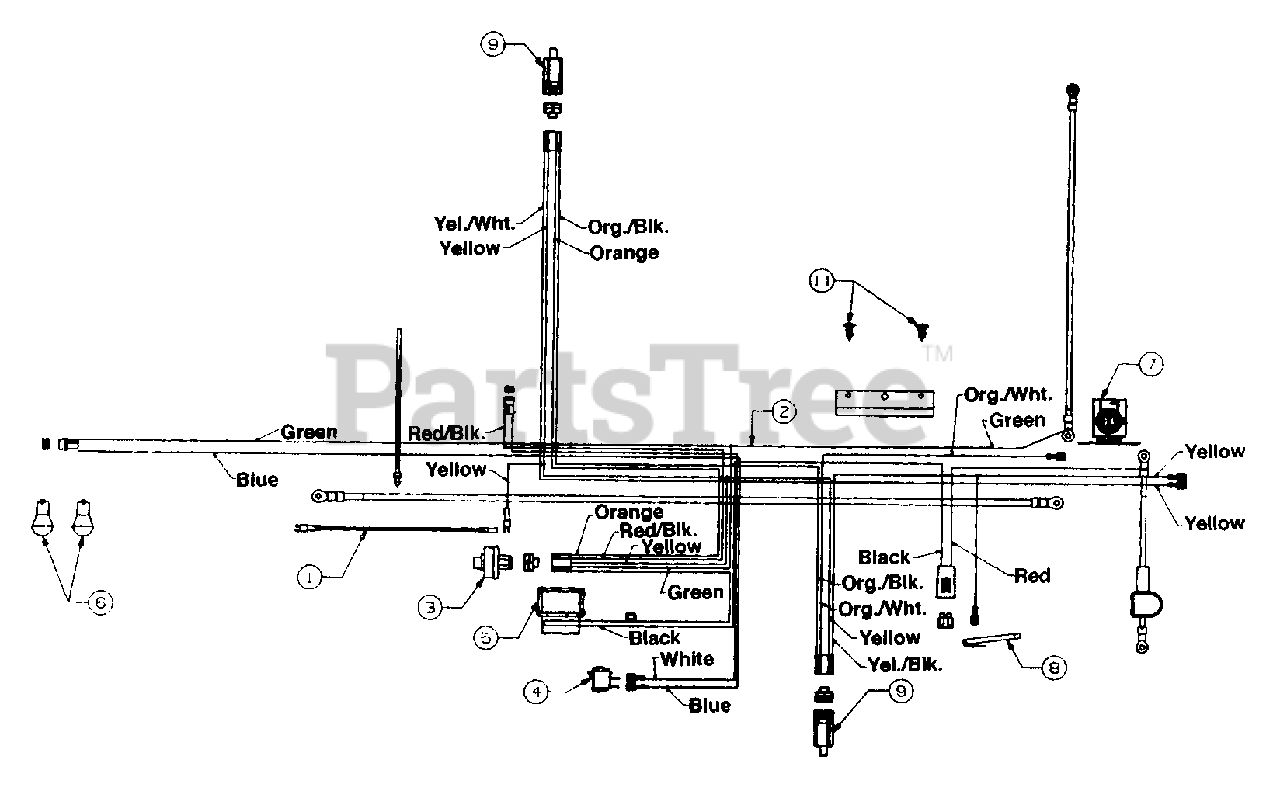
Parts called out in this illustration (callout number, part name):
1	Harness Adapter (Mag.)
2	Wire Harness w/Light Switch and Amp
3	Ignition Switch
4	Light Switch
5	Ammeter
6	Bulb (Headlight)
7	Solenoid
8	Safety Switch (Reverse)
9	Safety Switch
11	Ratchet
